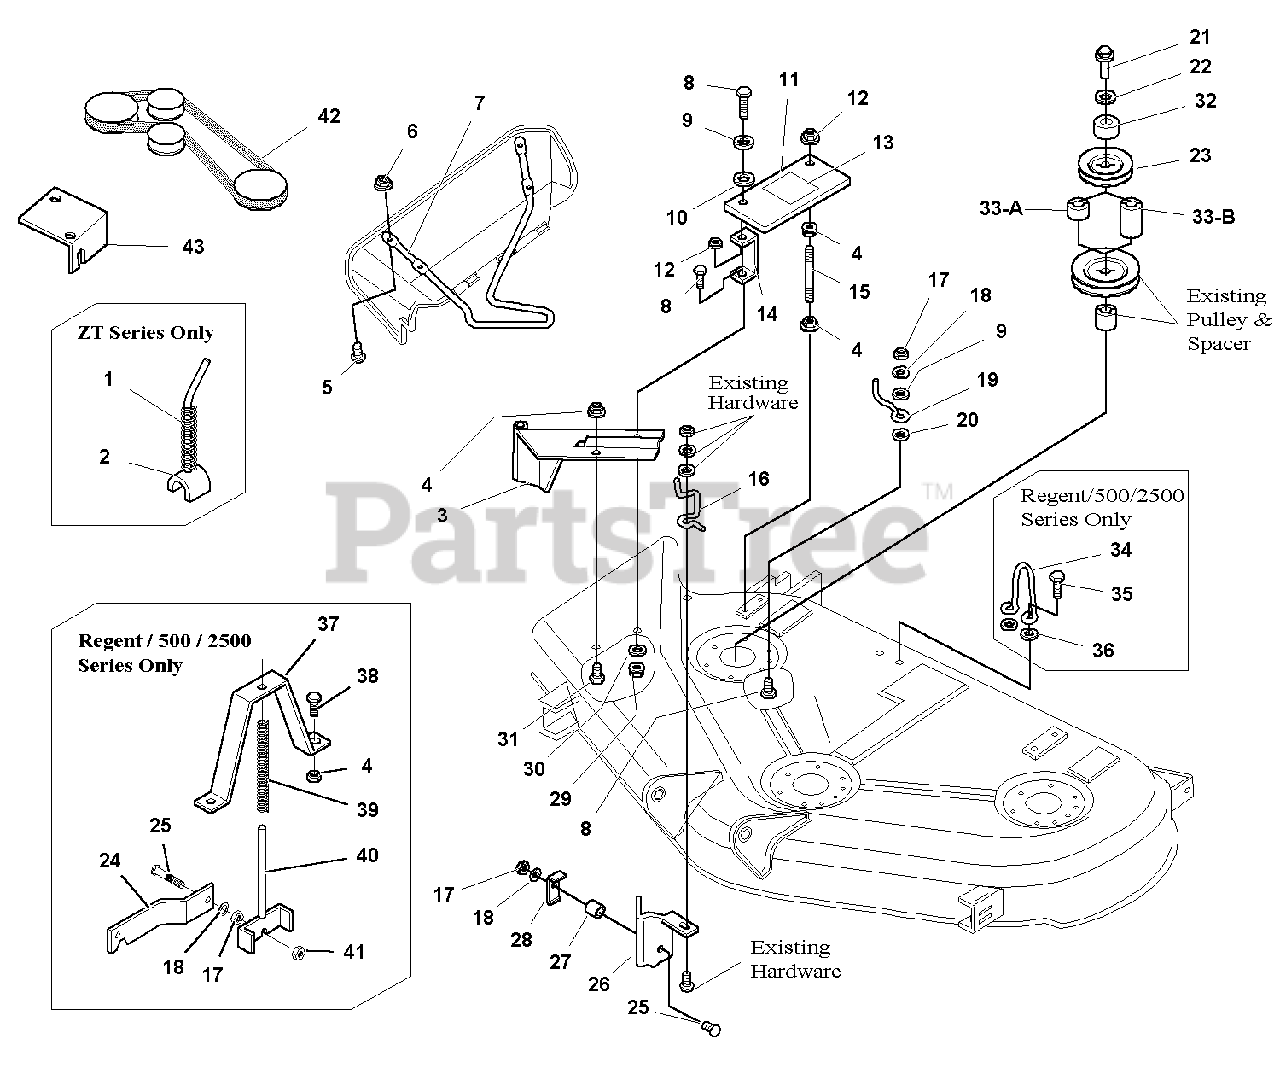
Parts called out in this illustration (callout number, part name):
1	SPRING, Compression
2	LEVER ASSY, ZT Counterbalance
3	PIVOT BRACKET ASSEMBLY
4	NUT, Hex Flange, Whizlock, 5/16-18
5	CAPSCREW, Truss Head, #10-24 x 3/4 Lg.
6	NUT, Nylock, #10-24
7	ROD, 3/8 Dia.
8	CAPSCREW, Hex Hd., 5/16-18 x 1 Lg.
9	WASHER, Flat, 11/32
10	WASHER, Nylon, 0.388 Dia.
11	COVER, Turbo Belt
12	NUT, Hex, Nylock, 5/16-18
13	DECAL, Warning
14	SUPPORT, Belt Cover
15	STUD, 5/16-18 x 5-3/4 Lg.
16	LATCH, Spring Wire
17	NUT, Hex, 5/16-18
18	LOCKWASHER, 5/16
20	WASHER, Flat, 3/8
21	NUT, Sleeve
22	WASHER, Belleville
23	PULLEY, 3-3/4" OD
25	CARRIAGE BOLT, 5/16-18 x 1-1/4 Lg.
26	BRACKET ASSEMBLY
29	NUT, Whiz-Lock, 5/16-18
30	WASHER, Flat, 13/32
31	CARRIAGE BOLT, 5/16-18 x 3/4 Lg.
32	SPACER, Cylinder, 3/4 Tall
33-A	HUB, Double, 3/4 Tall, Regent Series
33-B	HUB, Double, 1-9/32 Tall, ZT Series
34	UPSTOP, Wireform
35	CAPSCREW, Taptite, 5/16 x 1
36	WASHER, 5/16 x 1/4 Thick
37	BRACKET, Counterbalance
38	SCREW, Hex Whiz-Lock, 5/16-18 x 3/4
39	SPRING, Compression
40	ROD ASSEMBLY, Counterbalance
41	NUT, Flange, 2-Way Lock, 5/16-18
43	BRACKET, Mounting
